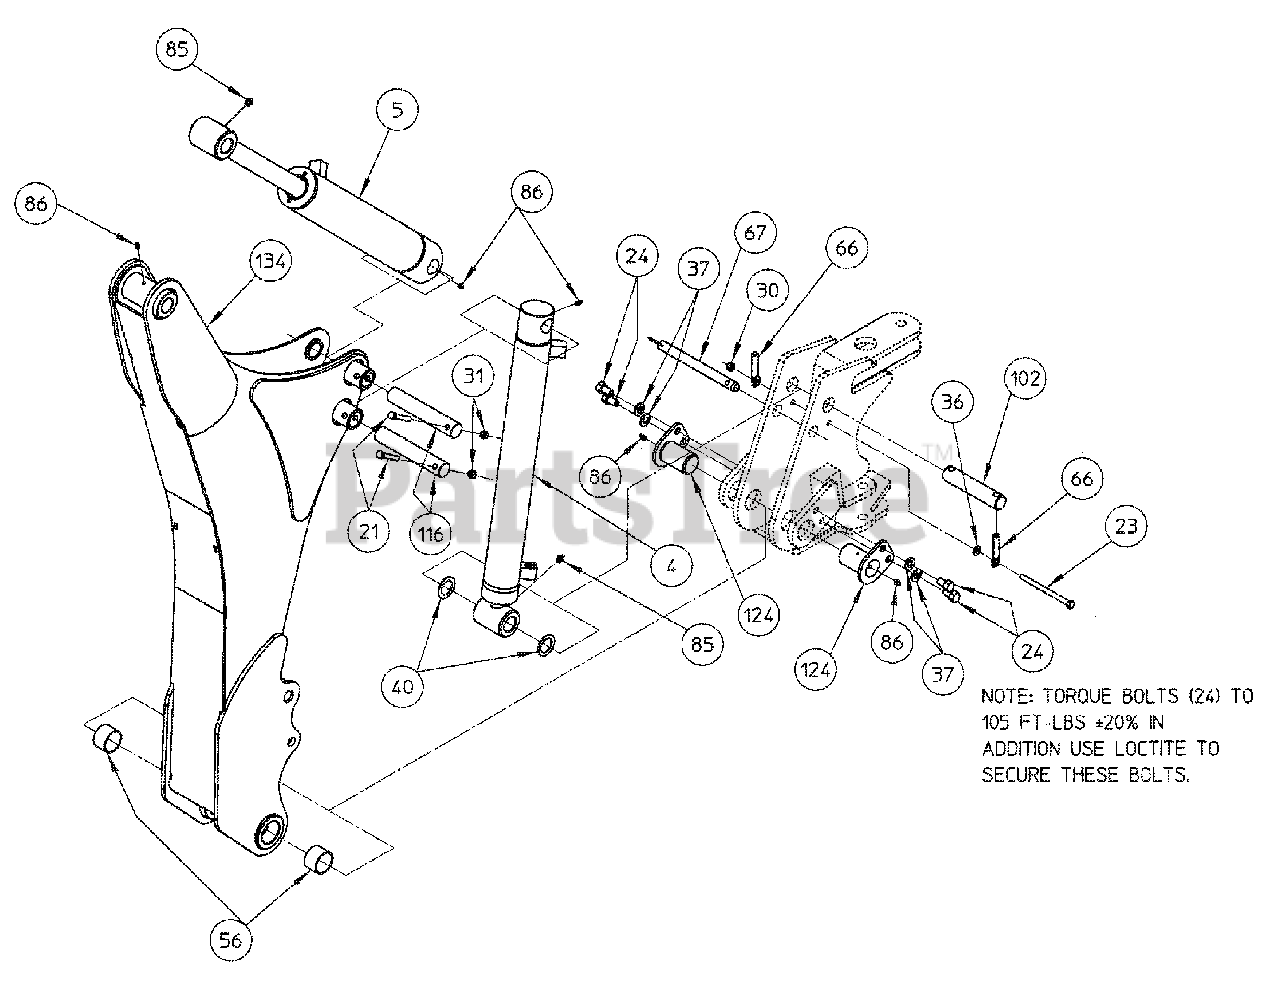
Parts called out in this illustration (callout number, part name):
1	Hydraulic Cylinder - Swing
2	Hydraulic Cylinder - Bucket
3	Hydraulic Cylinder - Stabilizer
4	Hydraulic Cylinder - Boom
5	Hydraulic Cylinder - Dipper
6	Bolt, Carriage 5/16 NC x 3/4"
7	Bolt, Carriage 5/16 NC x 1-1/4"
8	Bolt, 1/4 NC x 3/4"
9	Bolt, 5/16 NC x 3/4"
10	Bolt, 5/16 NC x 3/4" Thread Forming
11	Bolt, 5/16 NF x 3/4"
12	Bolt, 5/16 NF x 7/8"
13	Bolt, 5/16 NF x 1" Gr. 5
14	Bolt, 5/16 NF x 2-1/4" Gr. 5
15	Bolt, 5/16 NF x 2-1/2" Gr.5
16	Bolt, 5/16 NF x 4" Gr. 8
17	Bolt, 3/8 NF x 3/4"
18	Bolt, 3/8 NF x 1"
19	Bolt, 3/8 NF x 1-1/4"
20	Bolt, 3/8 NF x 1-3/4"
21	Bolt, 3/8 NF x 2-1/4"
22	Bolt, 3/8 NF x 2-3/4"
23	Bolt, 3/8 NC x 5-1/2" Long Gr.5
24	Bolt, 1/2 NF x 7/8"
25	Nut, 1/4 NC
26	Nut, 5/16NC
27	Locknut, 5/16 NC
28	Nut, 5/16 NF
29	Locknut, 5/16 NF
30	Lock Nut, 3/8NC
31	Locknut, 3/8 NF
32	Lockwasher, 1/4
33	Lockwasher, 5/16
34	Flat Washer. 5/16 STD
35	Washer, 5/16 SAE
36	Flat Washer, 3/8 SAE
37	Flat Washer, 1/2" Hardened
38	Machine Bushing, 1-1/4 OD x 3/4 ID x 14Ga.
39	Machine Bushing 1-1/2" OD x 1" ID x 18Ga.
40	Machine Bushing 1-7/8" OD x 1-1/4" ID x 18Ga.
41	Machine Bushing, 2-1/2 OD x 1-3/4ID x 18Ga
42	Cotter Pin, 3/32" Dia x 3/4"
43	Cotter Pin, 3/16 x 1-1/4"
44	Cotter Pin, 1/4 x 1-1/2"
45	Hair Pin Cotter, 3/64" Dia x 11/16"
47	Adapter Union, 9/16-18M x 3/8NPTF
48	Hydraulic Tee
49	Adapter Union, 3/4-16M x 3/8NPTF x Straight
50	Adapter Union, 3/8NPTM x 3/8NPTF x 90 degree
51	Adapter Union, 9/16-18M x 3/8NPTF x 90 degree
52	Adapter Union, 7/8-14M x 3/8 NPTF x 90 degree
53	Adapter Union, 3/4-16M x 3/8NPTF x 90 degree
54	Coupler Body 3/4-16F Thread
55	Coupler Nose 3/4-16F Thread
56	Garlock Bearing, 028DXR020
57	Bronze Bearing
58	Garlock Bearing, 028DXR016
59	Stabilizer Pad Weldment
60	Guide Link
61	Bucket Link
62	Street Pad
63	Clevis Pin, 3/16" Dia x 5/8"
64	Clevis Pin, 1/4" Dia x 7/8"
65	Pin Retainer
66	Pin Retainer
67	Boom Lock Pin
68	Swing Lock Pin
69	SMV Socket
70	SMV Bracket
72	Ball Joint - Shouldered
73	Ball Joint
74	Control Knob
75	Rubber Cap
76	Plastic Tie T150L
77	Plastic Tie T120 L
78	Plastic Tie T50L
80	Hose Sleeve FC425-16 X 30" Long
81	Hose Sleeve FC425-16 X 19" Long
82	Hose Sleeve FC425-16 X 48" Long
83	Hose Sleeve FC425-16 X 63" Long
84	Hose Sleeve FC425-16 X 79" Long
85	Grease Fitting
86	Grease Fitting (Two are part of #000187 Cyl.)
87	Grease Fitting (Two are part of #000187 Cyl.)
88	Hydraulic Hose, 3/8NPTM x 3/8NPTM x 20" long
89	Hydraulic Hose, 3/8NPTM x 3/8NPTM x 23" long
90	Hydraulic Hose, 3/8NPTM x 3/8NPTM x 30" long
91	Hydraulic Hose, 3/8NPTM x 3/8NPTM x 58" long
92	Hydraulic Hose, 3/8NPTM x 3/8NPTM x 76" long
93	Hydraulic Hose, 3/8NPTM x 3/8NPTM x 92" long
94	Hydraulic Hose, 3/8NPTM x 3/8NPTM x 110" long
95	Hyd. Hose, 3/8ID 3/8NPTF M x 3/4-16 Str O x 49"
96	Hyd. Hose, 3/8ID 3/8NPTF M x 3/4-16 Str O x 34"
97	Control Valve
98	Adapter Union, 7/16-20M x 3/8NPTF
99	Rear Shroud
100	Stabilizer Lever Control Rods
101	Control Rod
102	Pivot Pin, Boom Cyl. Rod 1-1/4" Dia. x 6" Long
103	Thrust Washer
104	Pivot Pin, Bucket 1"Dia. x 7-3/8" Long
105	SMV Socket Mount
106	Stabilizer Control Lever
107	Lever Bracket
108	Hose Clamp - Short
109	Pivot Pin, 3/4" Diameter x 4-1/16" Long
110	Pivot Pin, Dipperstick 1-1/4" Dia. x 7-15/16" Long
111	Pivot Pin, Stabilizer Leg
112	Pivot Pin Weldment
113	Pivot Pin, Stabilizer Pad 3/4" Dia. x 4-15/16" Long
114	Pivot Pin, Stabilizer Cyl. Rod
115	Pivot Pin, Bucket Cyl. Base 1" Dia. x 5-7/8" Long
116	Pivot Pin, Boom Cyl. Base 1-1/4" Dia. x 7-1/4" Long
117	Lower Pivot Pin Weldment
118	Seat Plate Weldment
119	RH Pivot Weldment
120	LH Pivot Weldment
122	Stabilizer Leg Weldment
123	Upper Pivot Pin Weldment
124	Pivot Pin Weldment, Boom 1-3/4" Dia. X 2-3/4" Lg
125	RH Toe Shield
126	LH Toe Shield
127	Hose Clamp - Long
128	Grab Bar Weldment
129	Mainframe Weldment
130	Valve Mount Weldment
131	Swing Frame Weldment
132	Front Shroud Weldment with Decals
133	Dipperstick Weldment
134	Boom Weldment
135	Right Hand Joystick Weldment
136	Left Hand Joystick Weldment
